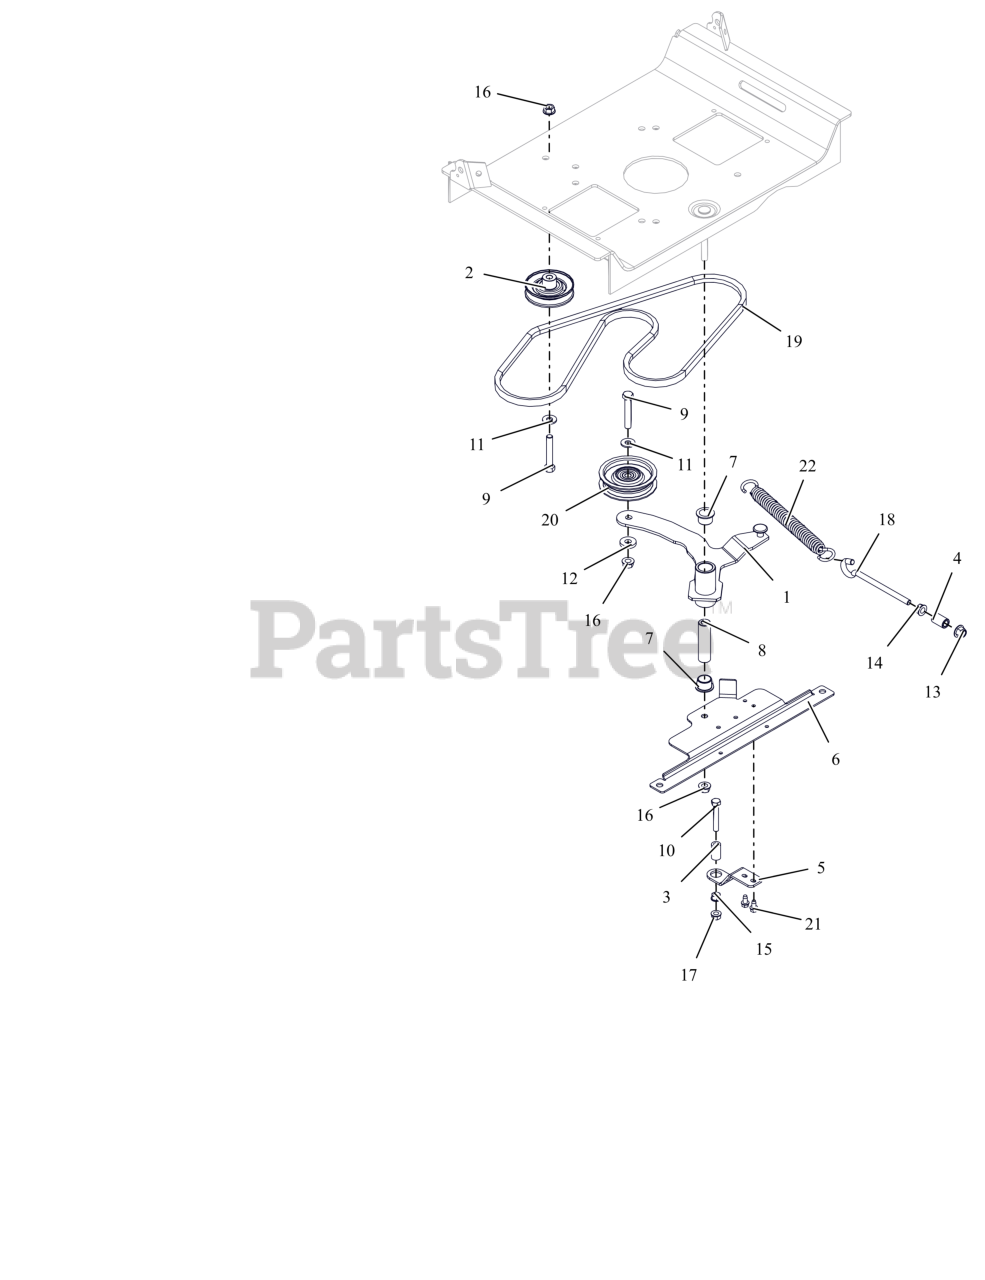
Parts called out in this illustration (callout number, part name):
1	WLDMT,GRD DRIVE IDLER ARM-LGR
2	IDLER, V-3.000 OD
3	SPACER, RUBBER 5/16 IDX1.0 LG
4	SPACER, .375X.625X.970 (PM)
5	BRKT, CLUTCH STOP (XL)
6	BRKT, IDLER ATTACHMENT (BLACK)
7	BSHG-FLG 0.75X0.875X.625X1.125
8	BUSHING, SLEEVE .38X.750X2.78
9	BLT,HEX .38-16X2.25 G5 ZCC
10	BLT, HEX .31-18X2.00 G5 ZCC
11	WSHR,FLT .375X.875X.083 ZCC
12	WSHR, FLT .406X1.00X.188 ZCC
13	NUT,NYL-FLG .38-16 GF ZCC
14	NUT, SPNLK-FLG .38-16 G5 ZCC
15	NUT,SPNLK-FLG .31-18 G5 ZCC
16	NUT-LK-TOP-FLG .38-16 ZC120
17	NUT-LK-TOP-FLG .312-18 GF ZCC
18	BOLT,.38-16 X 4.25-.62 DIA EYE
19	V-BELT, A-RAW EDGE
20	SHEAVE, IDLER -V .38 x 4.00
21	SCR-TAP .25-20X.50 HWH ZCC
22	SPRING, EXTENSION
